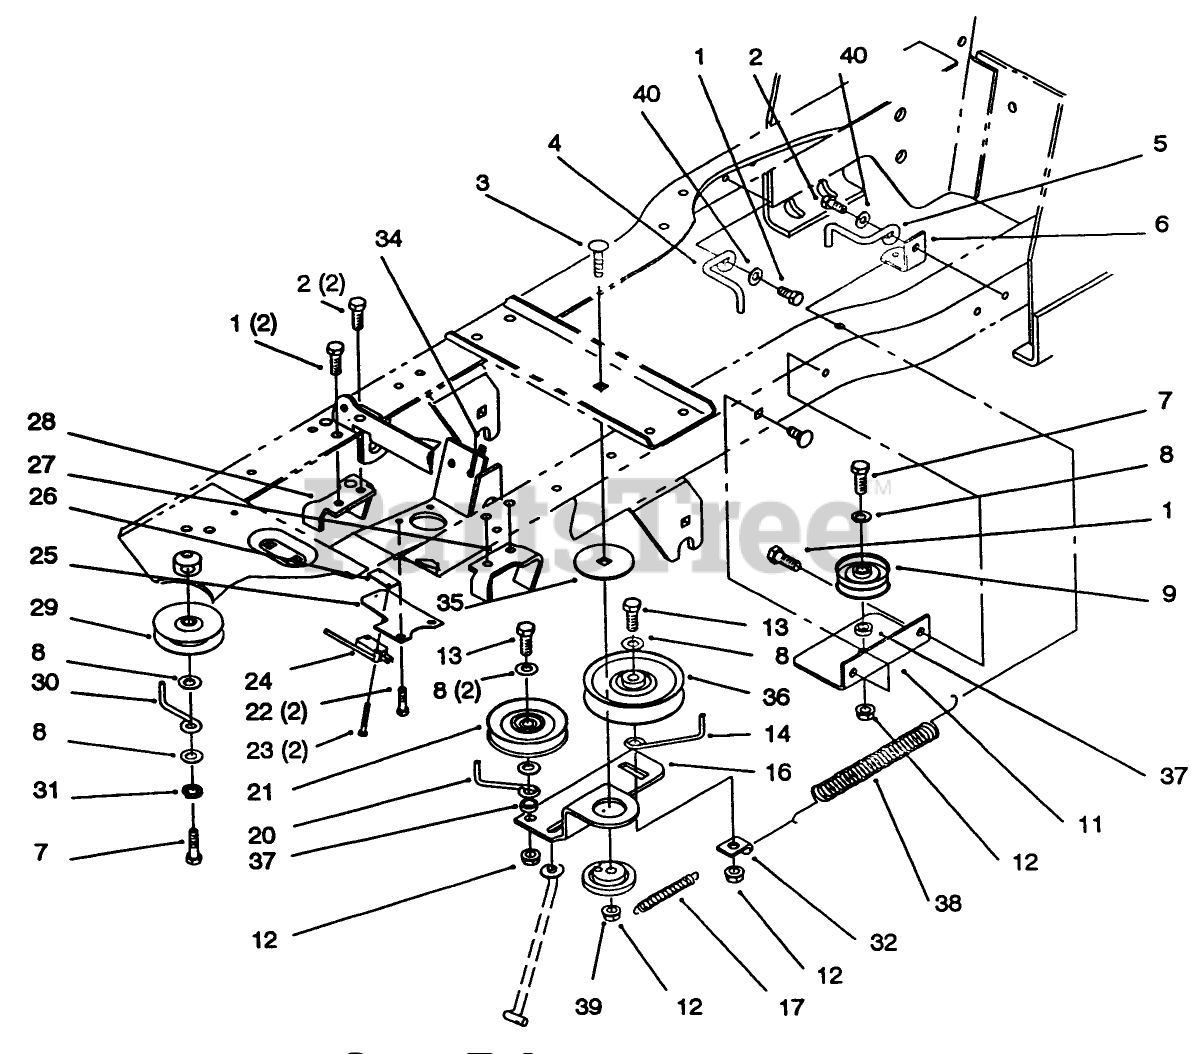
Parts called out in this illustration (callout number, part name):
1	SCREW-HWHTF
2	SCREW-HWHTF
3	BOLT-CARR
7	SCREW-HH
8	WASHER-FLAT
9	PULLEY IDLER NHI
11	BRACKET-REAR IDLER
12	NUT-LOCK, NI
13	SCREW-HH
14	GUIDE-BELT
16	ARM-IDLER
17	SPRING-EXTENSION
20	GUIDE-BELT
21	PULLEY-IDLER
22	SCREW-HWH
24	SWITCH-MICRO
26	NUT-SPEED
27	CLUTCH PEDAL STOP
28	BRAKE BRACKET PLATED
29	PULLEY-IDLER
30	GUIDE-BELT
31	WASHER-LOCK
32	CLIP - SPRING
34	TIE-CABLE
35	WASHER-BEARING
36	PULLEY-IDLER, FLAT
37	Spacer (Only On: 72043, 72103, 72063, 72083)
38	SPRING - CLUTCH
39	BUSHING
40	WASHER-PLAIN
